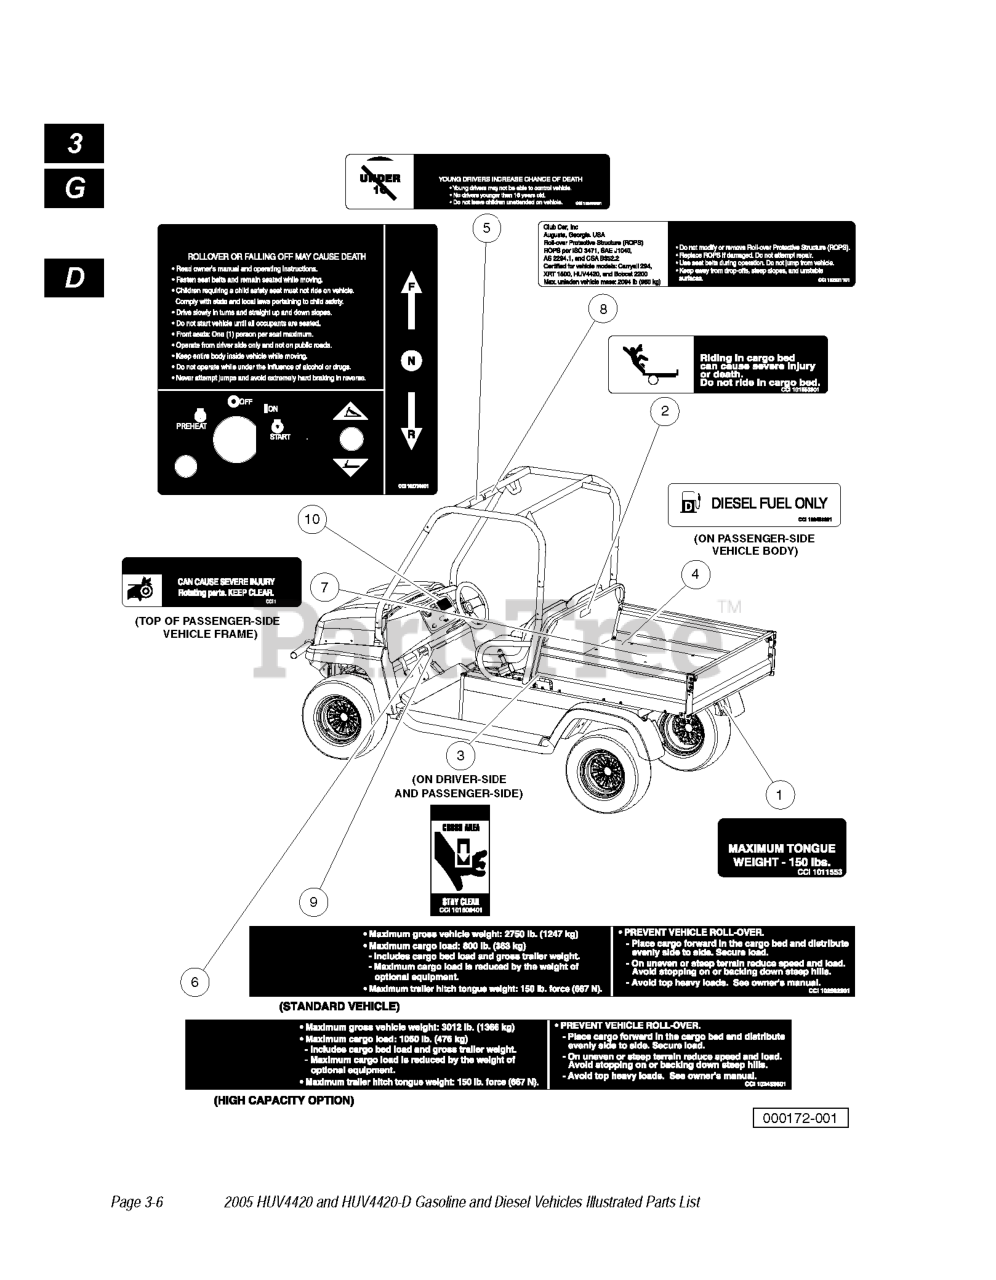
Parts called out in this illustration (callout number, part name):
1	DECAL, TRAILER HITCH
2	DECAL, BED LOAD WARNING
3	DECAL, CRUSH AREA WARNING
4	DECAL, DIESEL FUEL ONLY
5	DECAL, WARNING UNDER 16
6	DECAL, VEH LOAD HIGH CAPACITY
7	DECAL, WARNING ROTATING PARTS
8	DECAL, WARNING-CERTIFIED ROPS
9	DECAL, VEHICLE LOAD, 2750 LBS
10	DECAL-WARNING
